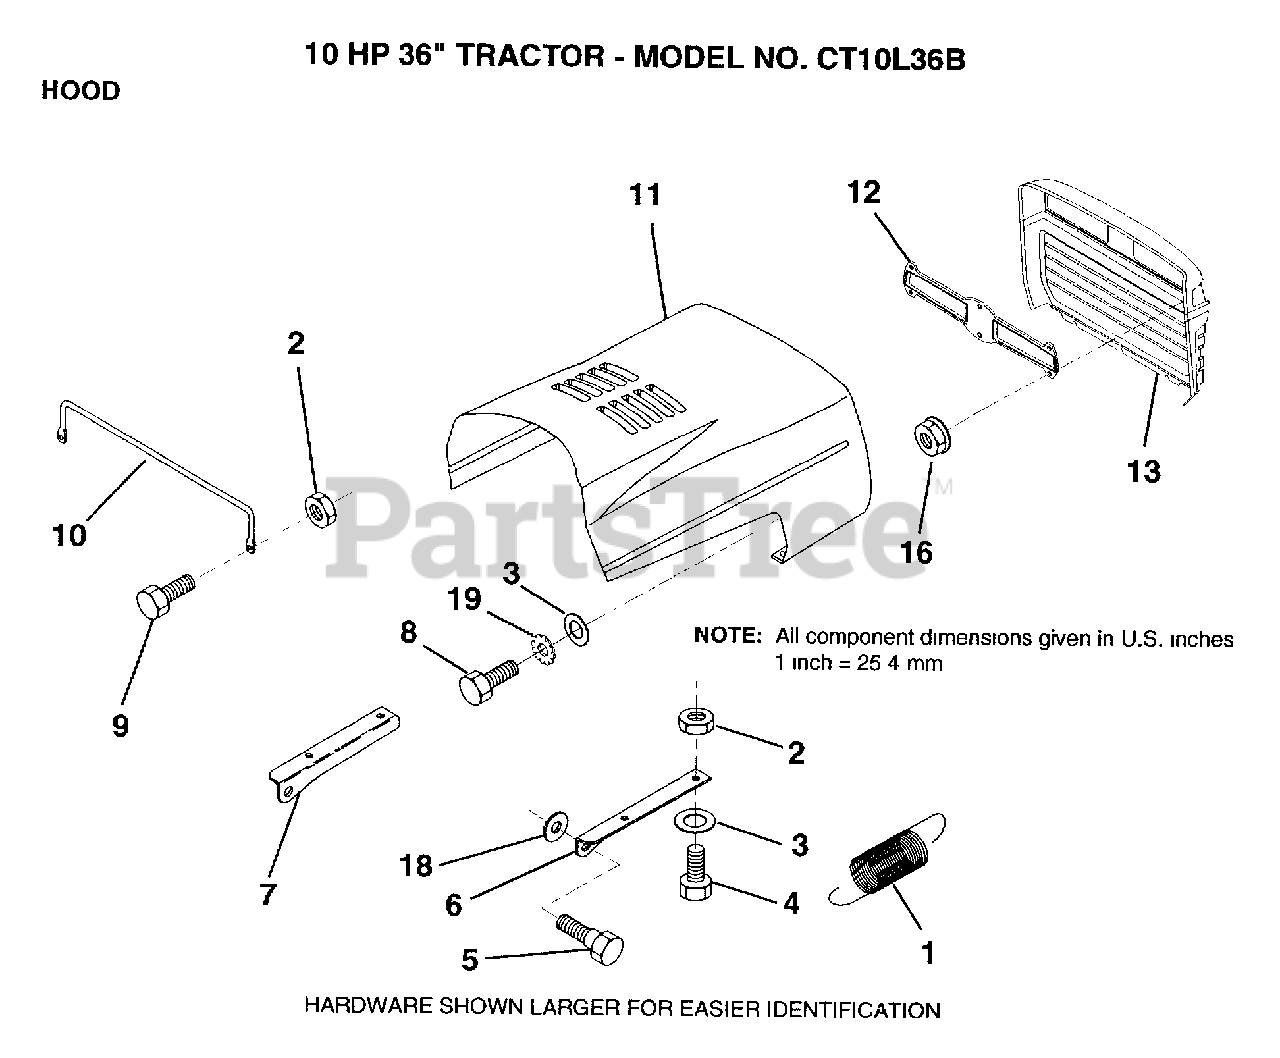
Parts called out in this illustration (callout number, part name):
1	EXT SPRING
2	NUT
3	WASHER
4	BOLT
6	BRKT HOOD RH
7	BRKT HOOD LH
10	"BRACE,HOOD"
11	HOOD
13	GRILL (BLACK)
16	NUT
18	WASHER
19	LOCKWASHER GT
